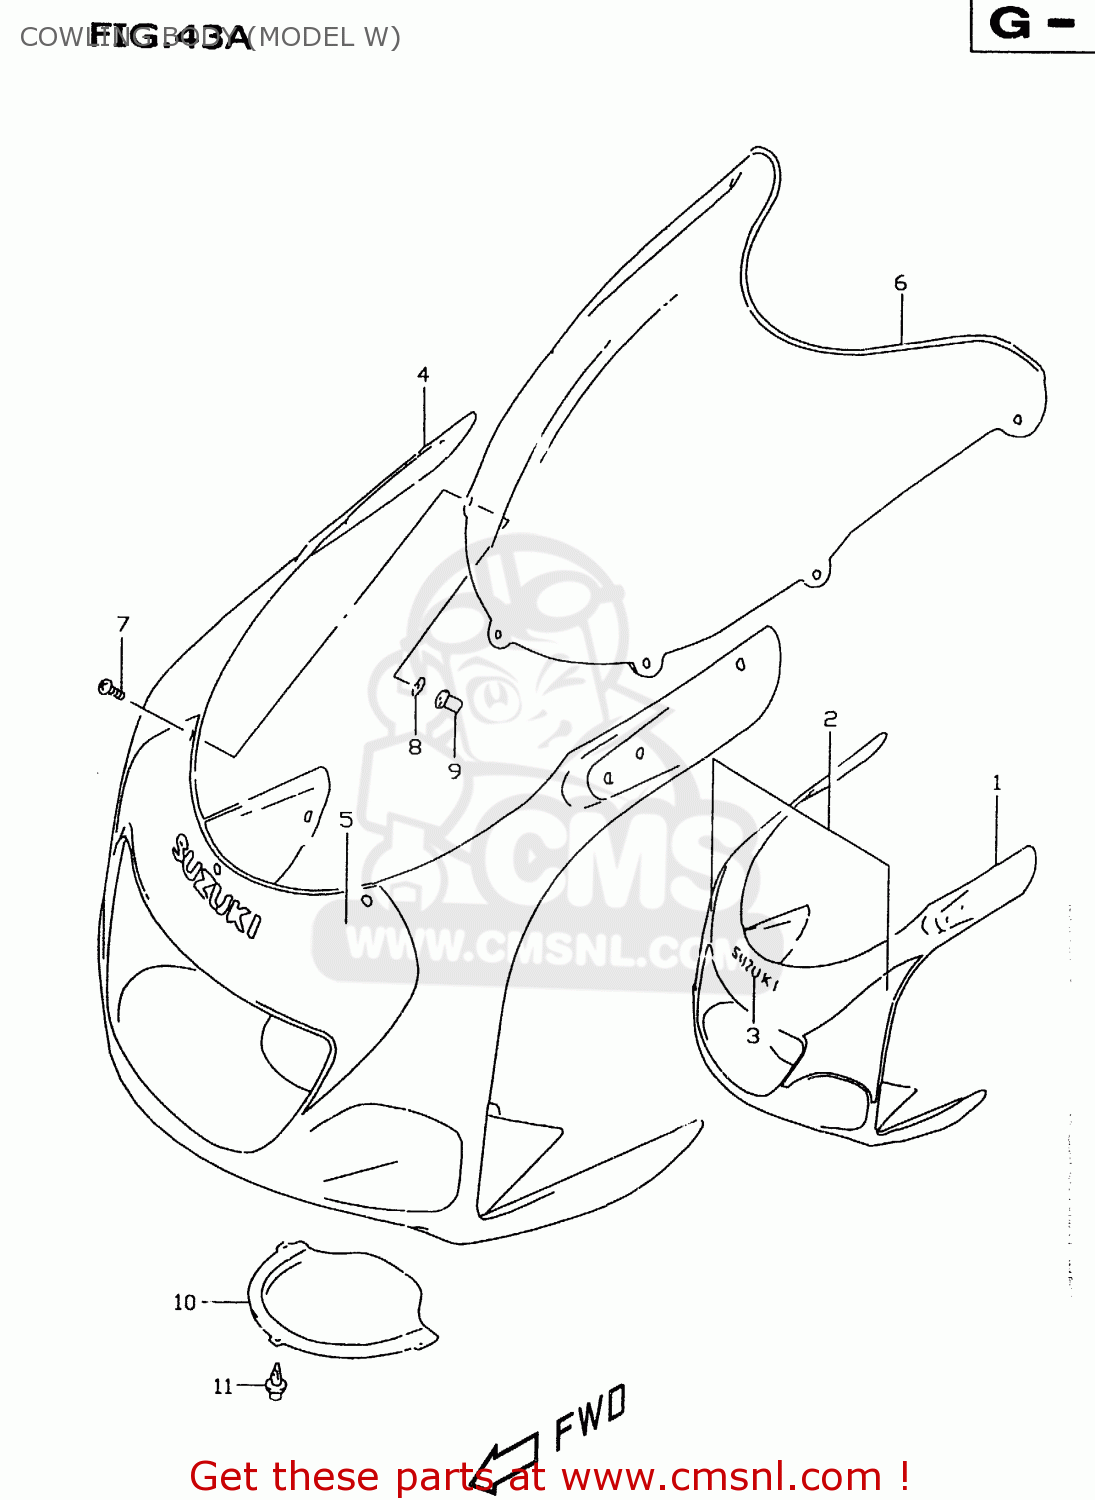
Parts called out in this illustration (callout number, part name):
1	COWLING ASSY,BODY
2	TAPE SET,COWL BODY
3	EMBLEM,FR
4	COWLING ASSY,BODY
5	TAPE SET,COWL BODY
6	WINDSCREEN
7	SCREW(5X14)
8	WASHER
9	NUT
10	LID,BODY COWL LWR
11	CLIP(BLACK)
